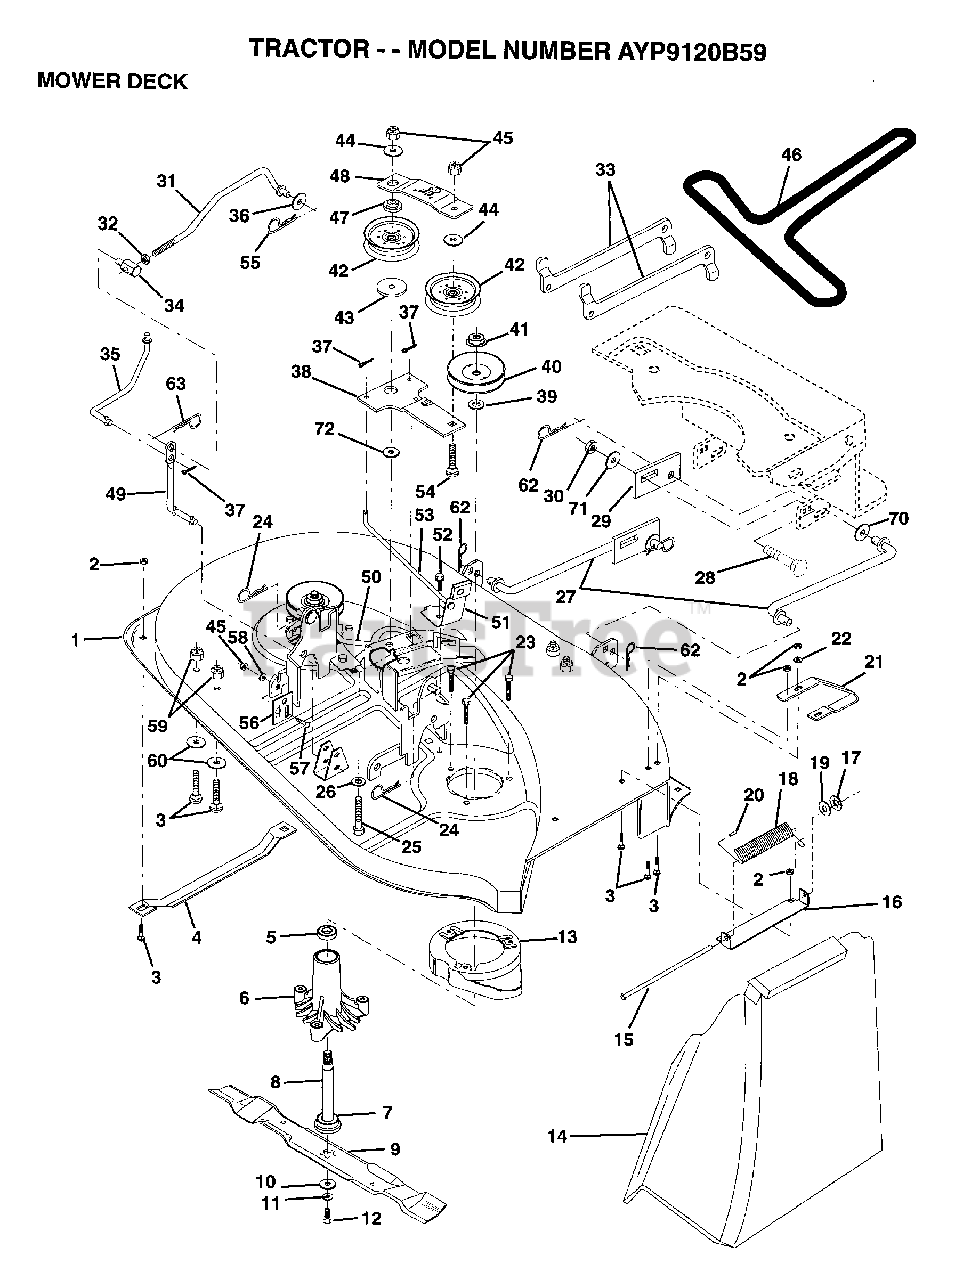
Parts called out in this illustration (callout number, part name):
1	MOWER.WELD.LR.38
3	BOLT
4	RUNNER-LH M
5	BEARING
6	HSG ASM MANDREL
7	BEARING.BALL
9	"BLADE.38""V.MULCH"
10	WASHER.HARD.BLADE
12	BLADE BOLT
14	DEFLECTOR-SHLD T
15	ROD-HINGE T
16	BRKT DEFLECTOR
17	NUT PUSH M
18	SPRING TORSION
19	WASHER
20	CAP-SLEEVE LT
21	RUNNER RH
22	WASHER M
24	RERAINER, SPRING
25	BOLT
26	WASHER GT
27	"LINK LIFT 38"""
28	IDLER ARM ASSY
29	PLATE SLIDE LINK
30	NUT
31	ROD.CLUTCH.PRIM
32	NUT
33	SUSP ARM REAR
34	TRUNNION
35	CLUTCH ROD SEC
36	WASHER
39	WASHER
42	PULLEY IDLER
43	SPACER RETAINER
44	WASHER GT
46	V BELT
47	RETAINER SPACER
48	IDLER ARM STIFF
49	PIVOT ROD
50	BRAKE ROD LH
51	BRAKE ASM
52	SCREW
53	BRAKE ROD RH
54	BOLT
55	SPRING.RETAINER
56	PLATE ADJ LINK LH
58	WASHER T
60	WASHER.34X.68X16
62	RETAINER.SPRING
63	RETAINER M
70	WASHER 1/2X1 1/4
71	WASHER PM
72	HARDENED WASHER
